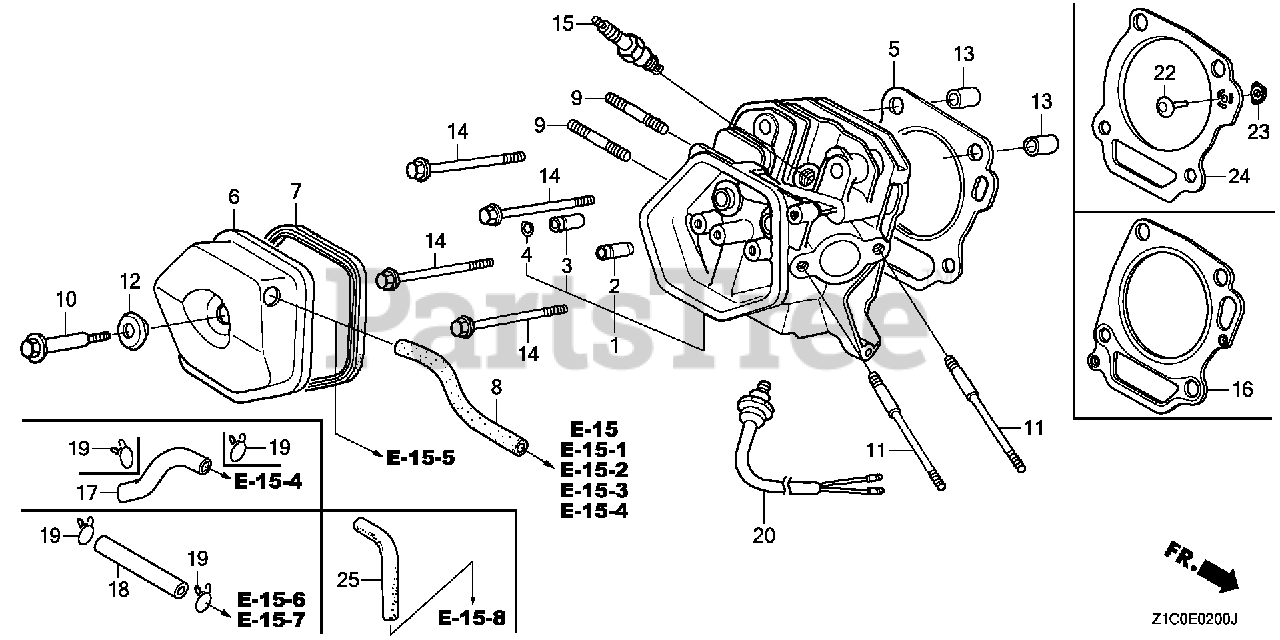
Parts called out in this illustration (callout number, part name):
1	CYLINDER HEAD
2	GUIDE, VALVE (OS)
3	GUIDE, EX. VALVE (OS)
4	CLIP, VALVE GUIDE
5	GASKET, CYLINDER HEAD Use up to Engine SN 2949254.
6	COVER, HEAD
7	GASKET, CYLINDER HEAD COVER
8	BULK HOSE, VACUUM (11X1000) (Honda Code 4537312). (11X105)
9	BOLT 2, STUD (8X32)
10	BOLT, HEAD COVER
11	BOLT, STUD (8X131.5)
12	WASHER, HEAD COVER
13	PIN A, DOWEL (12X20)
14	BOLT, FLANGE (10X80)
15	SPARK PLUG (BPR5ES) (NGK)
15	SPARK PLUG (BPR6ES) (NGK)
